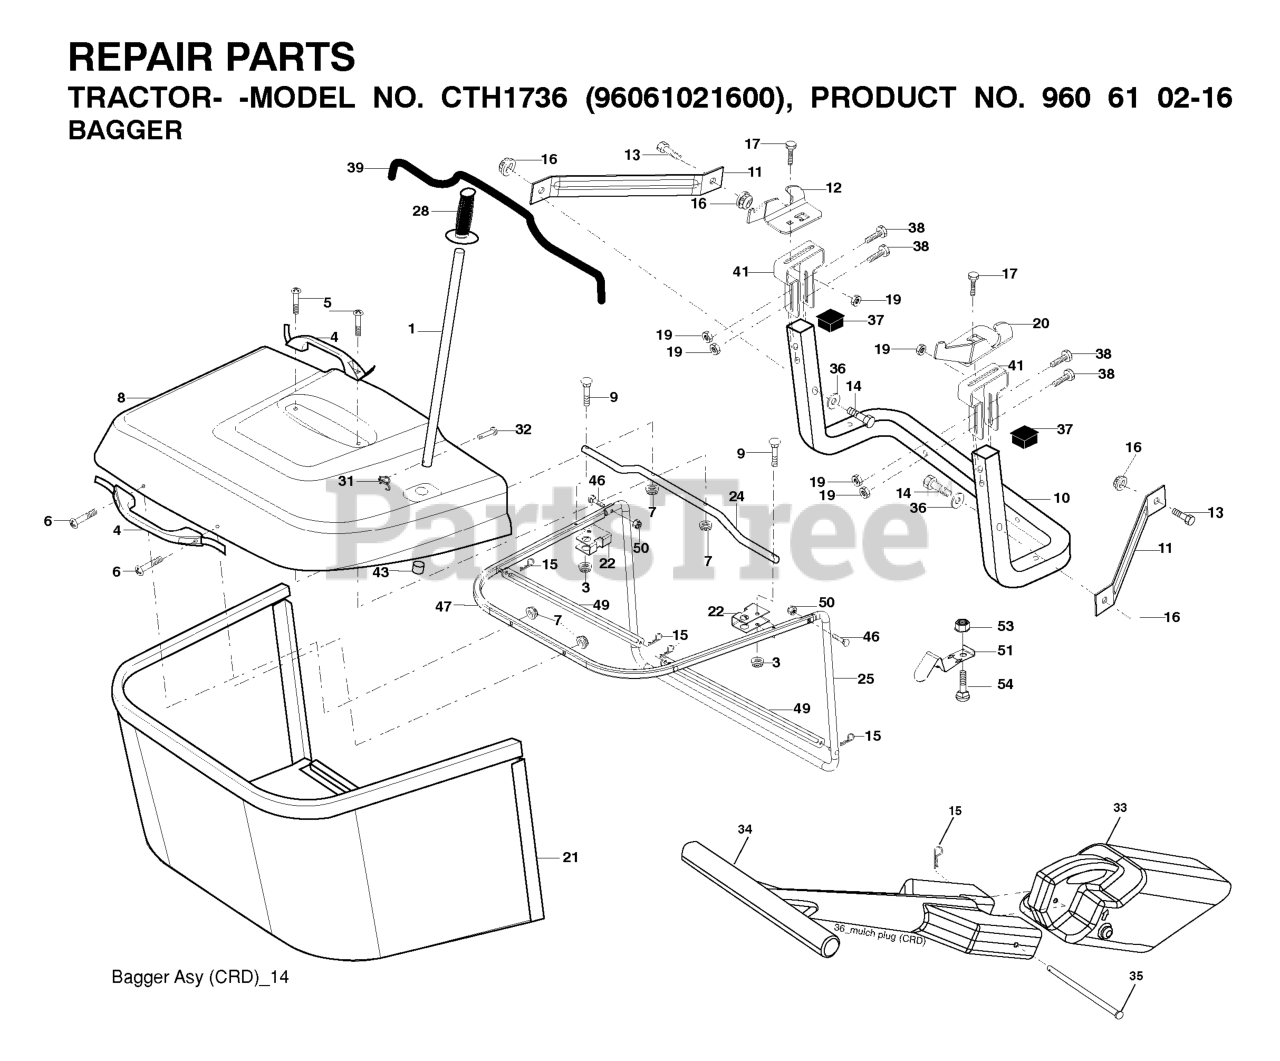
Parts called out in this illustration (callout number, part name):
1	TUBE HANDLE
3	NUT T
4	HANDLE.BAGGER.W/LVRS.BLK.CRD
5	SCREW.PAN.HEAD
6	REPL BY 532 75 00-29
8	COVER.PNT.BGR.CRD.WSLOTS.MS668
9	Bolt Carriage 1/4-20 x 2.25d x Gr.5
10	TUBE
11	BRACKET.SUPPORT.UPPER.BAG.CRD
12	BRKT PIVOT
14	BOLT-HEX EAK
15	RETAINER-SPRNG RB
16	NUT LOCK FLG 3/8-16 UNC
17	RP BOLT 5/16-18 X3/4 ZN/YEL GR
19	NUT LOCK HEX FLANGE 5/16-18
20	BRKT.PIVOT.RH.CRD
21	BAGGER.ASM.CRD.2007
22	BRKT.SIDE.BAG.CRD
24	TUBE.PIVOT.BAG.CRD.BLACK
25	PIPE
28	GRIP.HANDLE.BLACK
31	RETAINER CLIP
32	RIVET,DRILLED
33	PLUG.MULCHER.92 CRD
34	HANDLE.MULCHER.92.CRD (2 2)
36	WASHER
37	Plug Support Bagger CRD
38	BOLT.5/16-18X2.5
39	SEAL.TRIM.37'
41	BRKT.VERT.ADJ.BAGGER.CRD
43	PLUG, TUBING END
46	BOLT.CARRIAGE.5/16-18
47	PIPE
49	ROD
50	NUT.71038.31-18.HEX.NYLOCK
51	LATCH
53	NUT
54	BOLT
